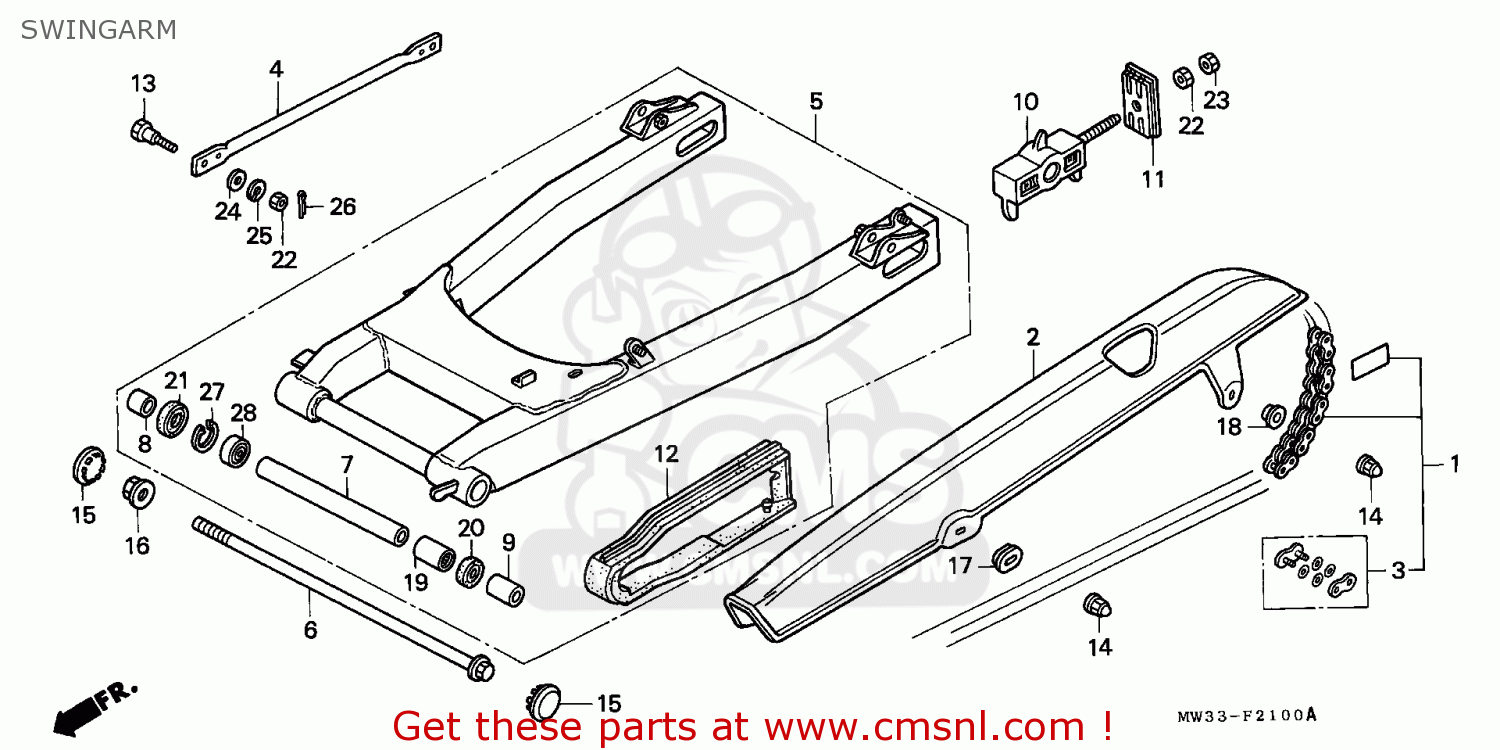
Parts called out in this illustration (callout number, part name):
1	CHAIN SET,DRIVE(R
2	CASE,DRIVE CHAIN
5	SWINGARM ASS*NH1*
6	BOLT RR FORK PIVO
7	COLLAR,PIVOT DIST
8	COLL,B,RR.FORK PV
9	COLLAR,B.PIVOT.
10	COLLAR COMP.,CHAI
11	PL CHAIN TENSION
12	SLIDER,CHAIN
14	NUT,CAP,6MM
15	CAP,PIVOT
16	NUT,U,14MM
17	WASHER,6X9
18	WASH CHAIN CASE
19	NEEDLE BRG
20	OIL SEAL 22X31X5
21	DUST SEAL,22X35X7
23	NUT,HEX 8MM
27	CIRCLIP IN 35MM
28	B/BRG RAD N/COM
